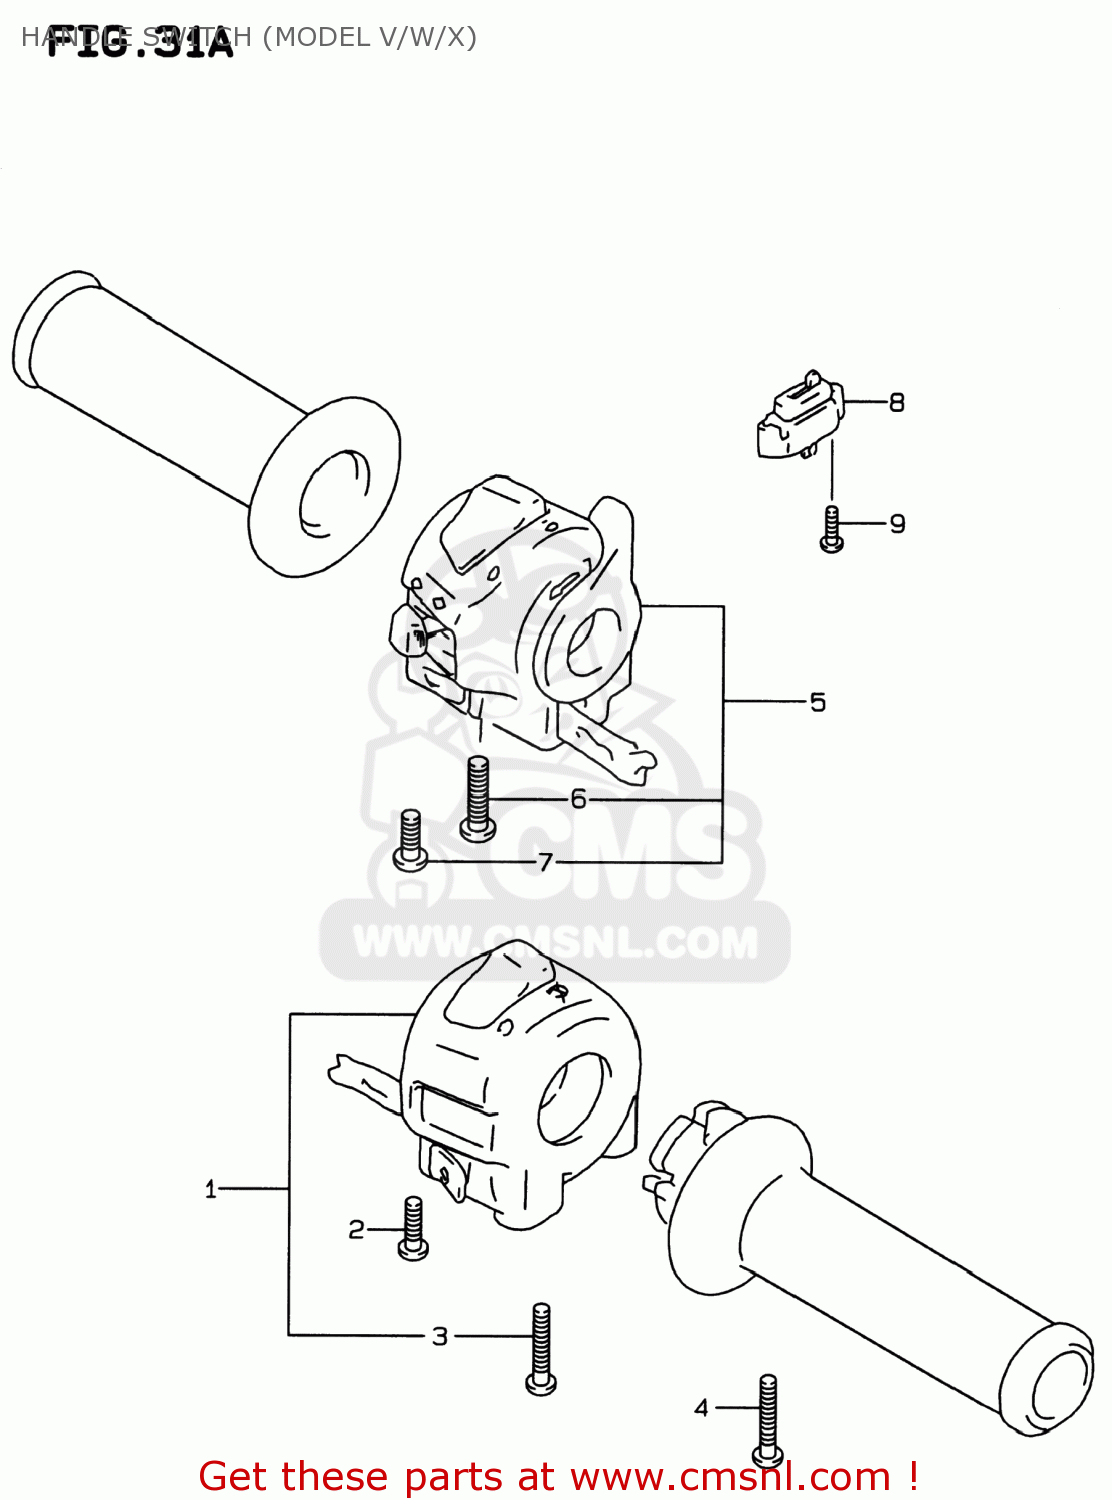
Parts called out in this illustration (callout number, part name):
1	SWITCH ASSY,HANDLE,R
2	SCREW
3	SCREW
4	SCREW
5	SWITCH ASSY,HANDLE,L
6	SCREW
7	SCREW
8	SWITCH ASSY,CLUTCH
9	SCREW
